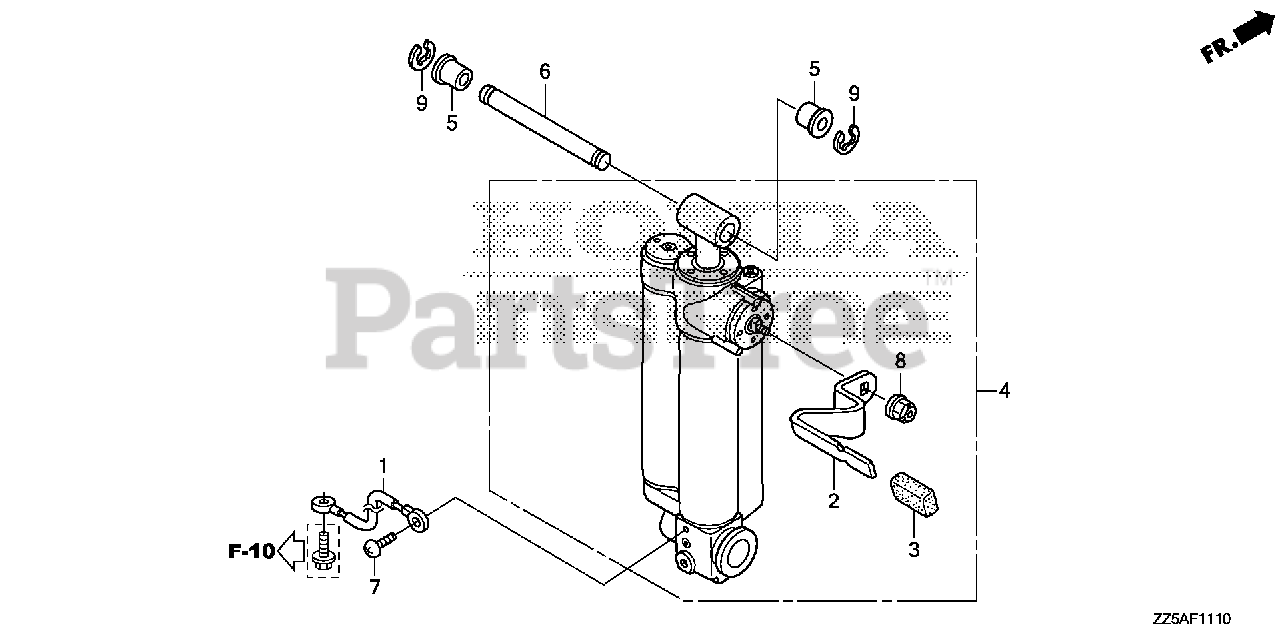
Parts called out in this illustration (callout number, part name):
1	WIRE, LEAD (1.5X116MM)
2	LEVER, TILT
3	GRIP, TILT LEVER
4	SHOCK ABSORBER ASSY.
5	BUSH, CYLINDER (UPPER)
6	PIN, CYLINDER (UPPER)
7	SCREW, PAN (6X8)
8	NUT, SELF-LOCK (6MM)
9	E-RING (10MM)
